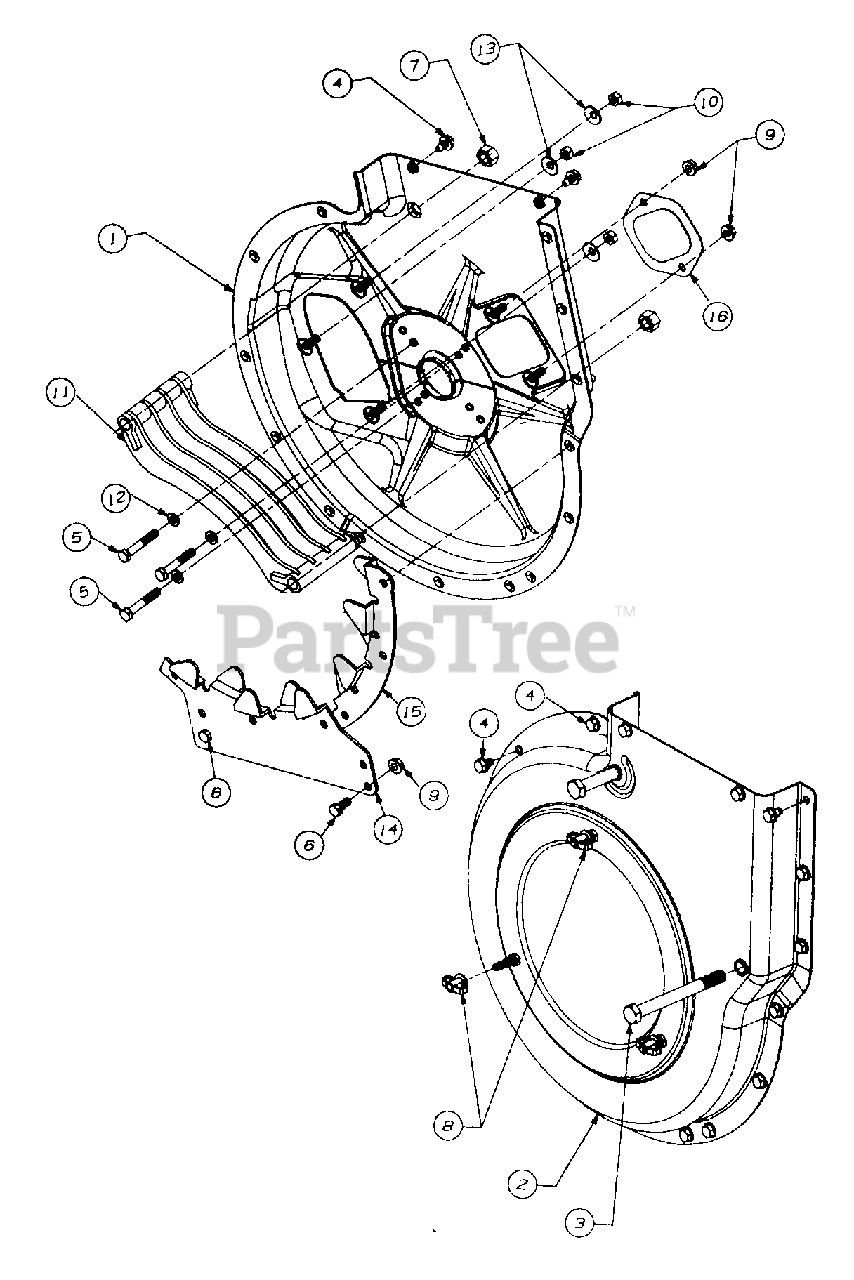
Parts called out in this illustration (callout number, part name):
4	SCREW - HEX SELF TAP
7	NUT - HEX LOCK
9	NUT - HEX LOCK
10	NUT - HEX (GR 5)
12	WASHER - LOCK
13	WASHER - BELL
